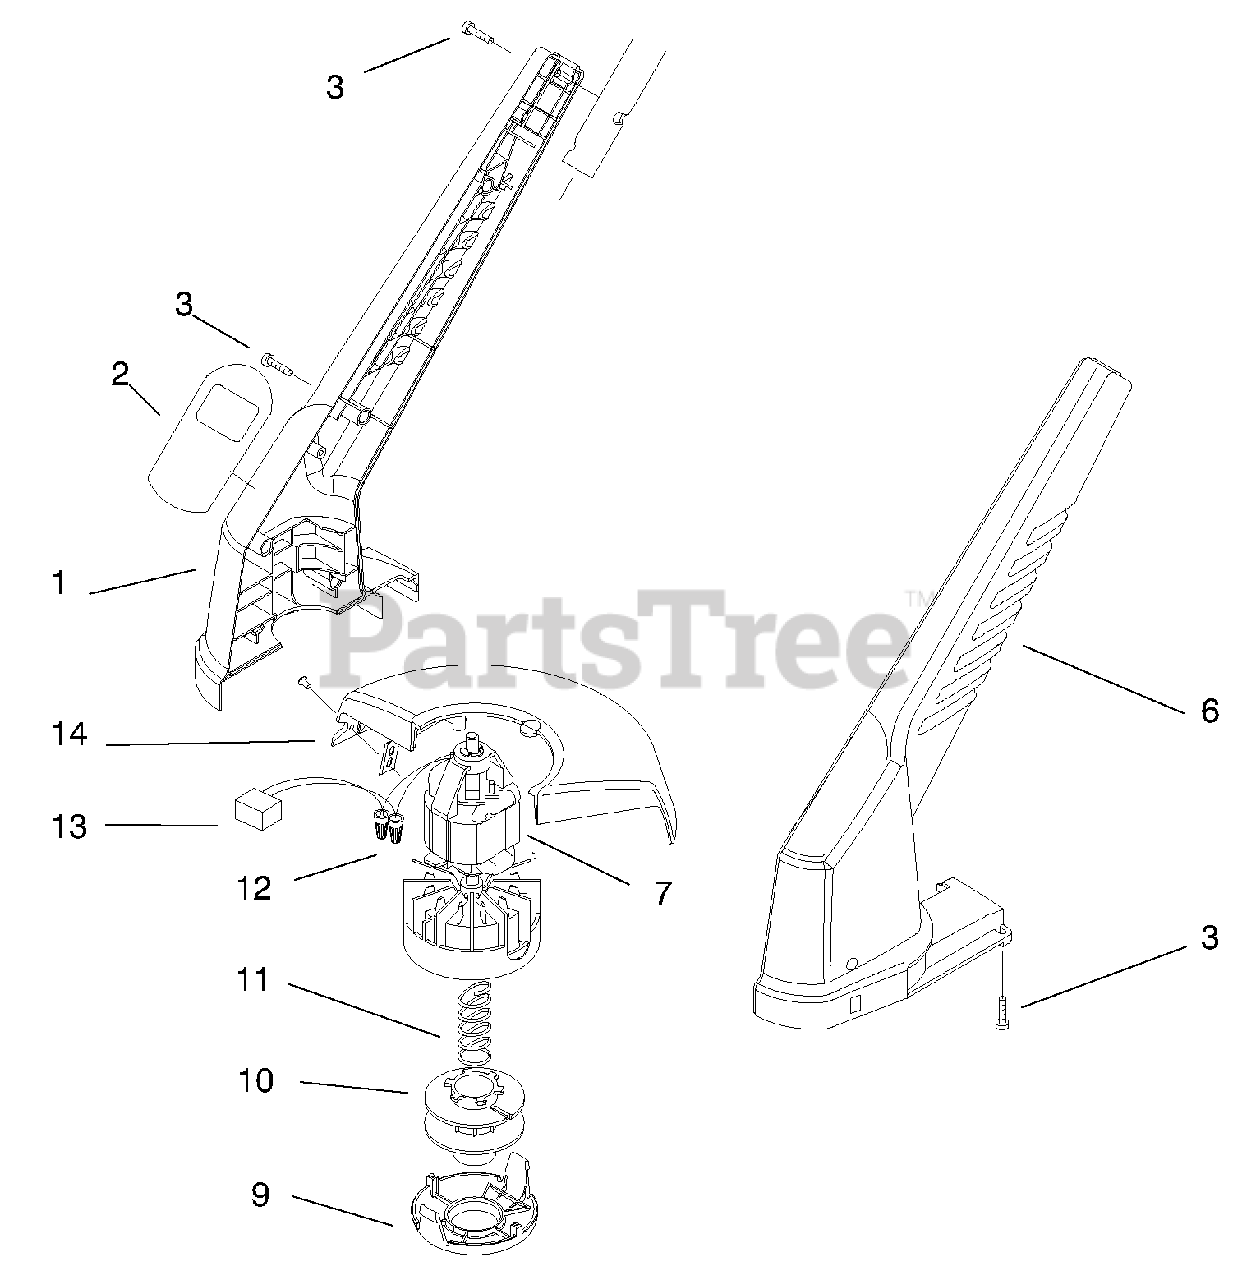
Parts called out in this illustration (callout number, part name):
1	Housing R.H.
2	Decal-30CM Trimmer
3	Screw-Pan Hd.
6	Housing L.H.
7	Motor Assembly-Trimmer
10	Spool
12	Connector-Wire Nut
